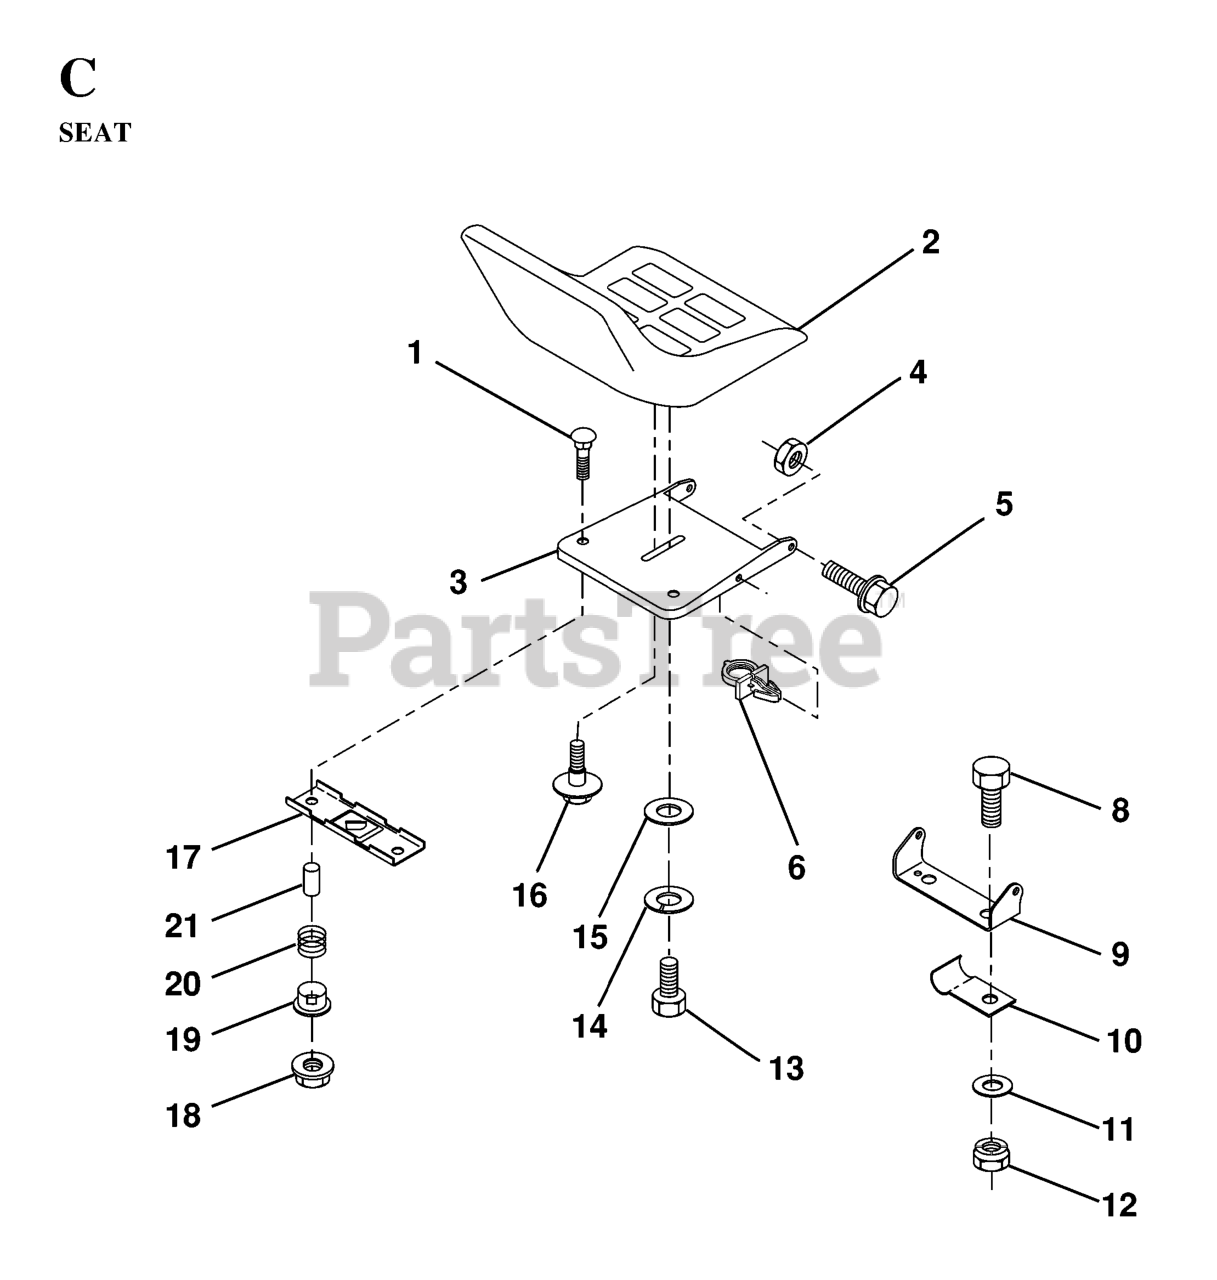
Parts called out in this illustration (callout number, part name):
1	Bolt Rdhd. Sht. Nk 1/4-20 x 1-3/8
2	SEAT
3	PAN, SEAT
4	NUT.71038.31-18.HEX.NYLOCK
5	BOLT SHOULDER 5/16-18
8	BOLT
9	SEAT PIVOT BRKT
10	CLIP,INSULATOR
11	WASHER 12/32X2X10GA
12	NUT
13	BOLT
14	LOCKWASHER
16	BOLT,SHOULD
17	BRKT SWITCH
18	NUT T
21	SPACER SPLIT 28X.96
